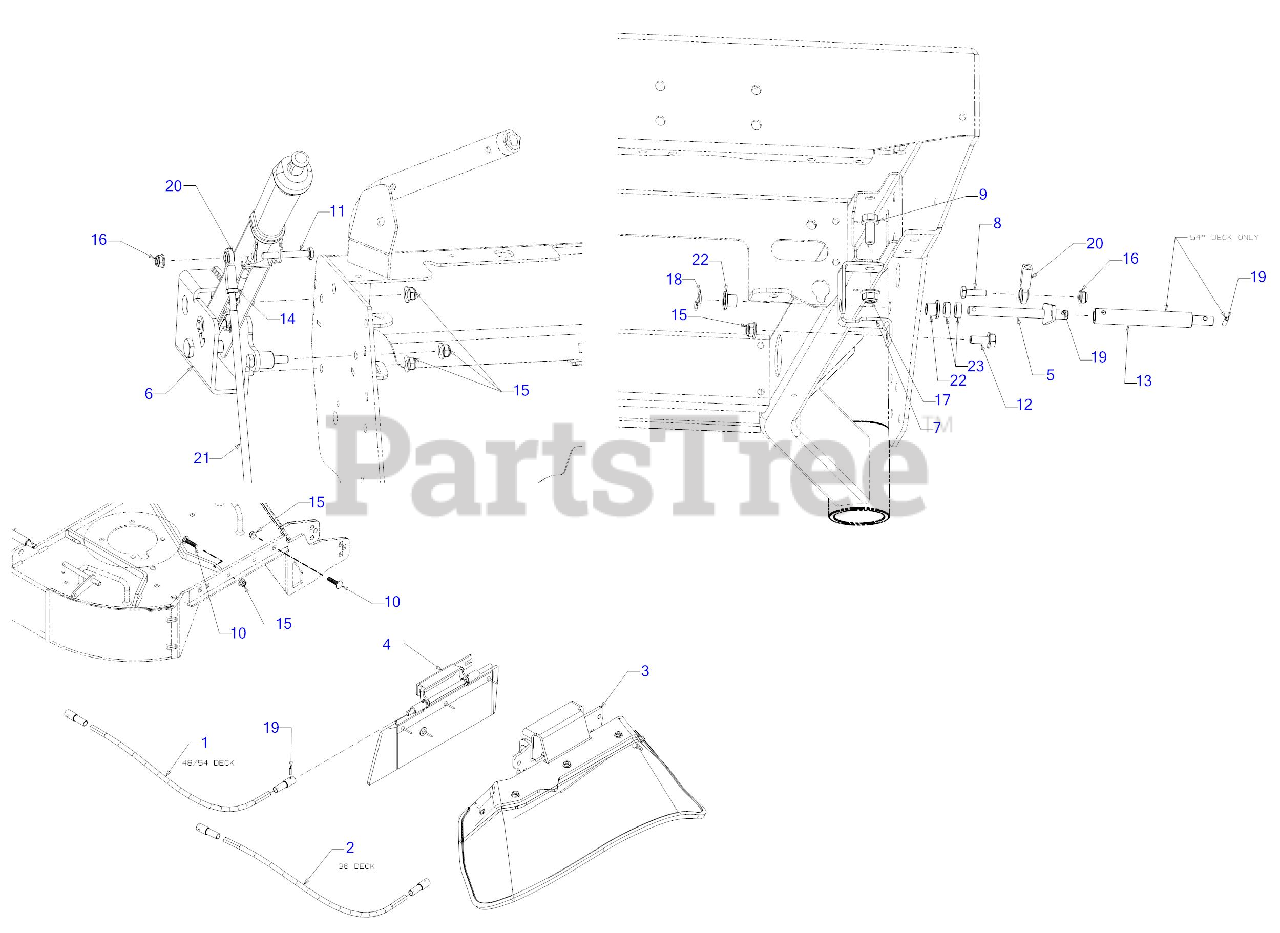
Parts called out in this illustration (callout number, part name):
1	CHUTE CONTROL CABLE ASSEMBLY
2	CHUTE CONTROL CABLE ASSEMBLY
3	54/60" CHUTE DOOR KIT
3	CHUTE SUPPORT PLATE
3	WASHER .355X1.25X.048THK
3	SCREW 5/16-18 x 1.0 GR5
3	HEX FLANGE NUT
3	CARRIAGE BOLT 5/16-18 x 1.00
3	FLAT WASHER
4	NOT SERVICEABLE
4	DEFLECTING DOOR BRACKET
4	POP RIVET .187 DIA
4	BLADE RESTRICTOR FLAP 48/54/60
4	BUSHING .380 ID
4	ROLL PIN 5/32" x .688"
4	DECK DOOR SUPPORT PLATE
5	DISCHARGE DOOR SHAFT ASSEMBLY
6	NOT SERVICEABLE
6	DOOR HANDLE LIFT ROD
6	YOKE 1/4-28
6	COMPRESSION SPRING
6	HEX NUT 1/4-28
6	LIFT HANDLE GRIP
6	CLEVIS PIN 0.25 x 2.00
6	LIFT HANDLE BUTTON
6	FLAT WASHER
6	SHOULDER SCREW .498 DIA x 1.450-THD
6	SPACER .34 x .75 x .63 LG
6	HANDLE MOUNTING BRACKET ASSEMBLY
6	SCREW 5/16-18 x 1.5 LG
6	BOW TIE COTTER PIN 1/4-5/16
7	BELLCRANK MOUNTING BRACKET
8	HEX SCREW 1/4-20 x .875 GR5
9	SCREW 3/8-16 x .875 GR5
10	CARRIAGE BOLT 5/16-18 X 1.25
11	SCREW 1/4-20 x 2 GR5
12	SCREW 5/16-18 x .750 GR8
13	ADAPTER SHAFT 4.25"
14	HEX JAM NUT 1/4-28
15	FLANGE LOCK NUT 5/16-18
16	FLANGE LOCK NUT
18	BOW TIE COTTER PIN 1/4-5/16
19	ROLL PIN 5/32" x .688"
20	END ROD (RH)
21	DISCHARGE DOOR ROD
22	FLANGE BEARING
23	SPACER-.380 ID X.625 OD x .227
